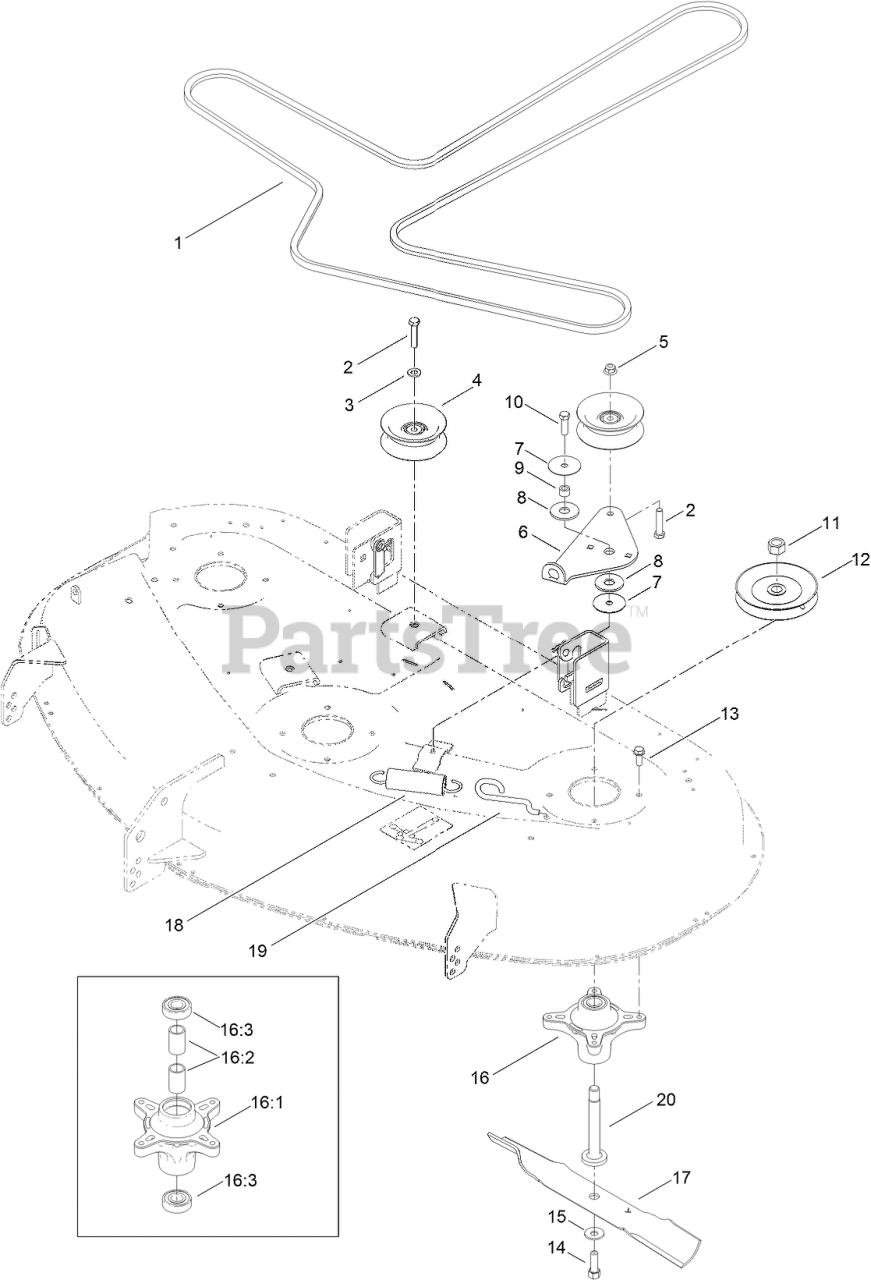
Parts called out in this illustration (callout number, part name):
1	V-BELT
2	SCREW-HH
3	WASHER-FLAT
4	PULLEY-IDLER, FLAT
5	NUT-HF, NI
6	ARM-IDLER
7	WASHER
8	WASHER-FRICTION, COMPOSITE
9	SPACER
10	SCREW-HH
11	NUT-HEX
12	PULLEY
13	SCREW-TAPTITE
14	SCREW-HH
15	WASHER-BELLEVILLE
16	SPINDLE ASM
16:1	SPINDLE
16:2	SPACER
16:3	BEARING-BALL
17	BLADE-HI LIFT
18	SPRING-EXTENSION
19	HOOK-RETURN, SPRING
20	SHAFT-SPINDLE
